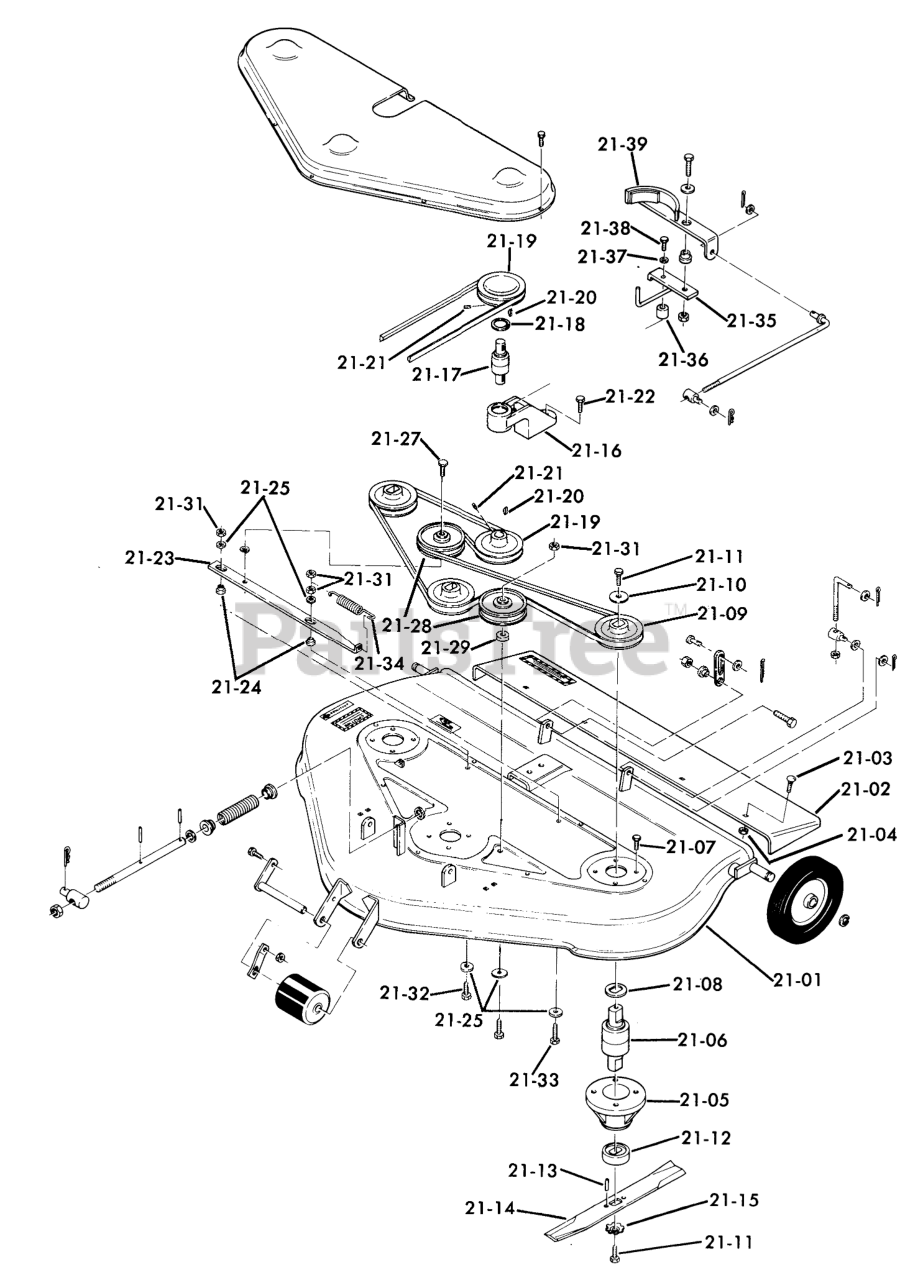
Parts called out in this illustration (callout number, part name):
21-01	Rear Discharge Mower Deck
21-01	Side Discharge Mower Deck
21-02	Extension-Chute
21-03	Bolt-Carriage
21-04	NUT
21-05	HOUSING-BEARING B
21-06	BEARING
21-07	Bolt
21-08	WASHER-DOUBLE D
21-09	PULLEY-MOWER DRIVE
21-10	WASHER
21-11	Bolt
21-12	Cup-Spindle
21-13	SPIROL ROLL PIN
21-14	BLADE KIT
21-15	WASHER
21-16	HOUSING DRIVE BRG R
21-17	BEARING INTEG SHAFT
21-18	Snap Ring
21-19	Pulley
21-20	KEY-WOODRUFF
21-21	Set Screw
21-22	Bolt
21-23	BAR-IDLER SUPPORT
21-24	SPACER
21-25	WASHER
21-27	BOLT HEX SPECIAL
21-28	Idler Pulley
21-29	SPACER
21-31	Nut
21-32	Bolt
21-33	Bolt
21-34	SPRING-EXTENSION
21-35	Pivot Bracket
21-36	Spacer
21-37	LOCKWASHER
21-38	BOLT
21-39	Support and Brake Lining
